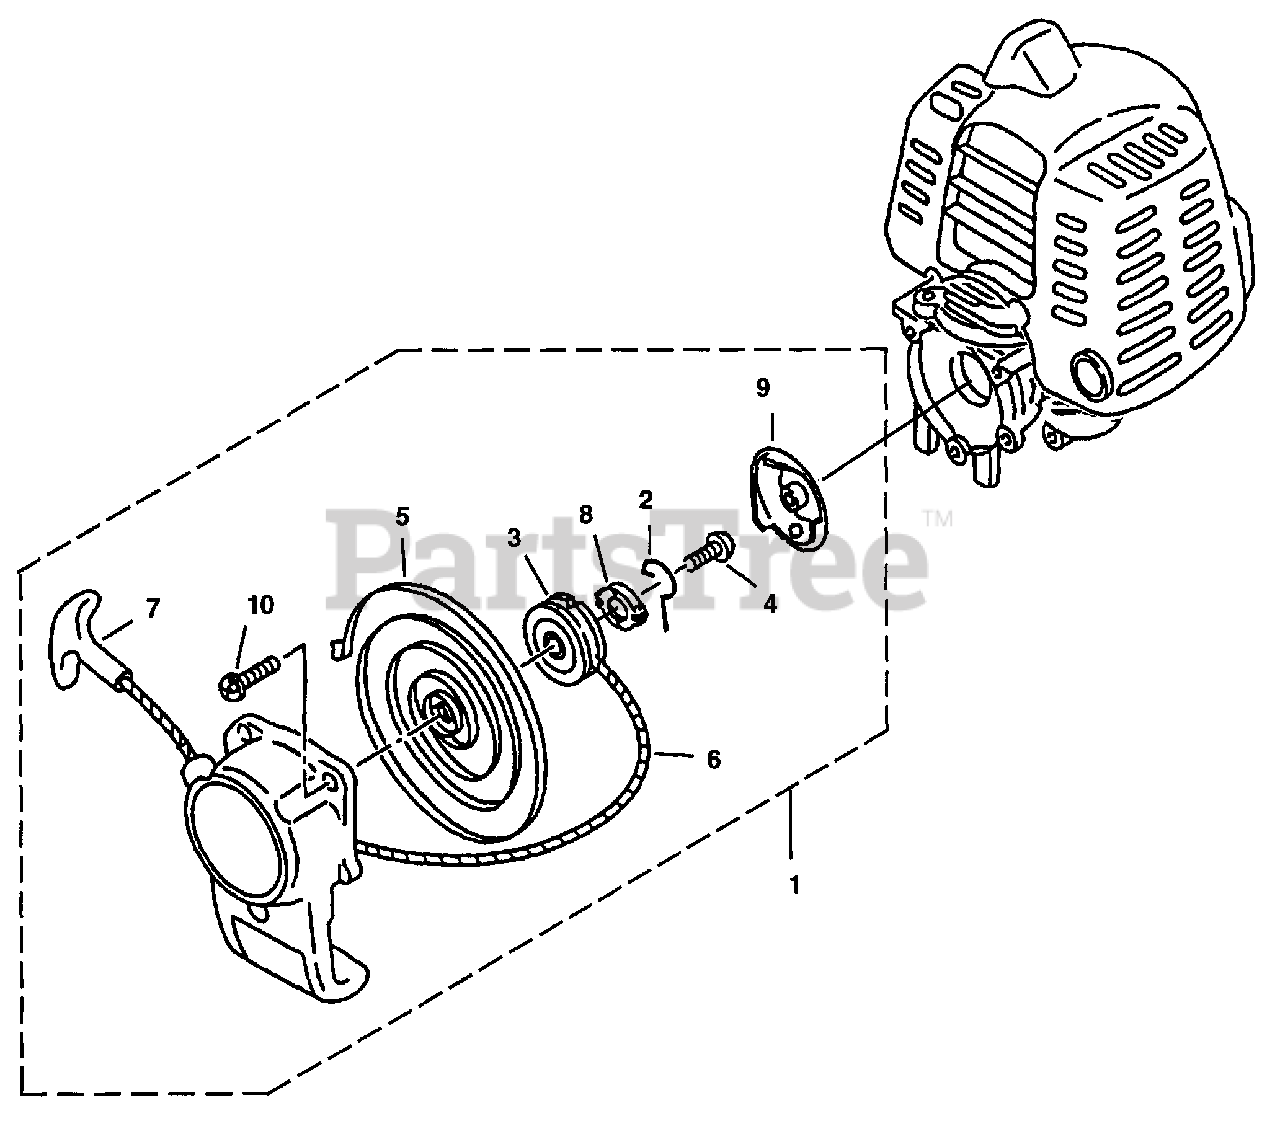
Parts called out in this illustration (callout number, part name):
1	STARTER COMPLETE
2	SWING ARM
4	SCREW-Set
5	SPRING-Return
6	ROPE-Starter
9	STARTER CUP
10	SCREW ASSEMBLY (M4 x 25)
